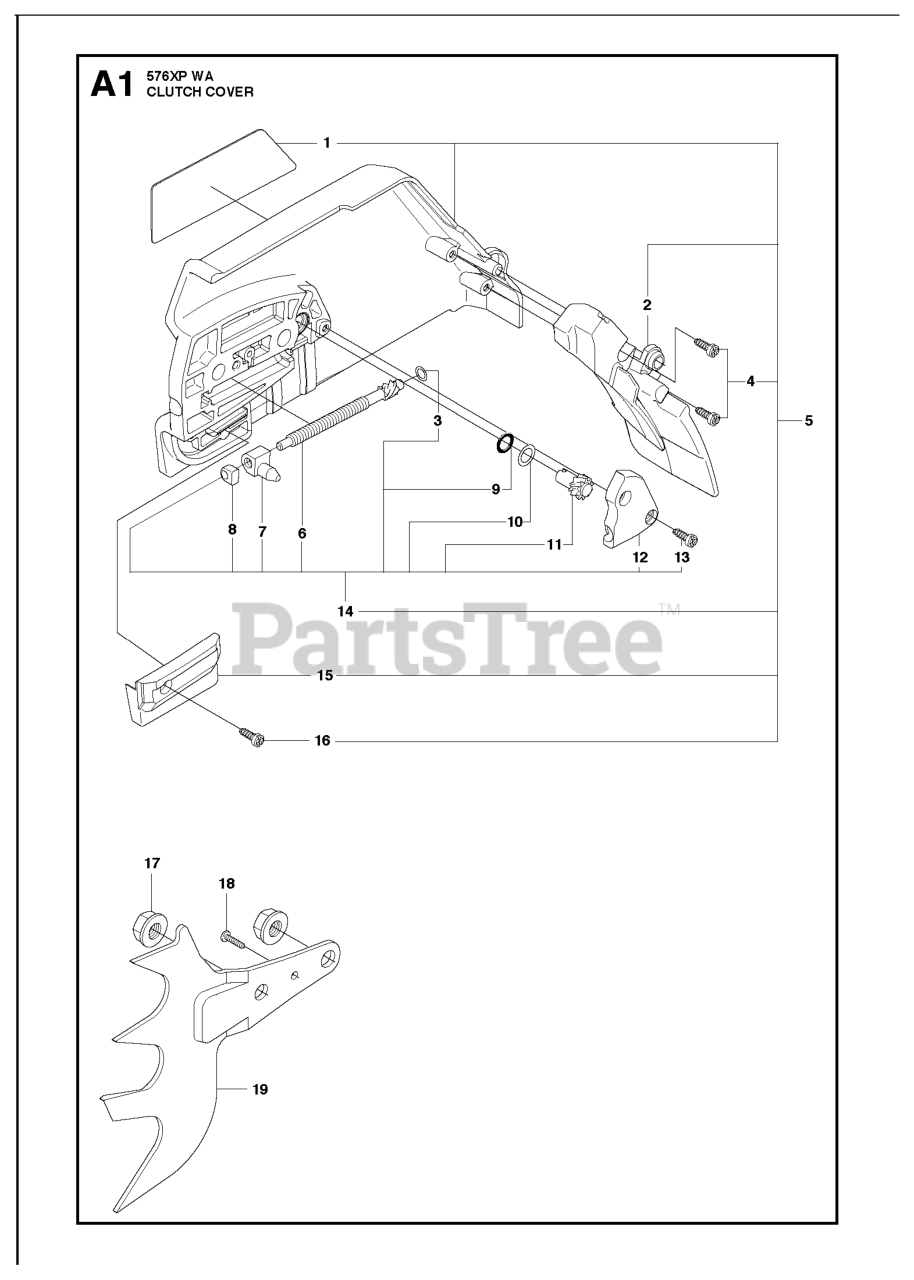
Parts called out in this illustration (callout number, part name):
5	CLUTCH COVER ASSY
6	WORM SCREW / ADJUSTER
11	WORM WHEEL
14	KIT-CHAIN TENSIONER
15	CHAIN GUIDE
17	NUT M8 FLANGE
19	FELLING DOG
